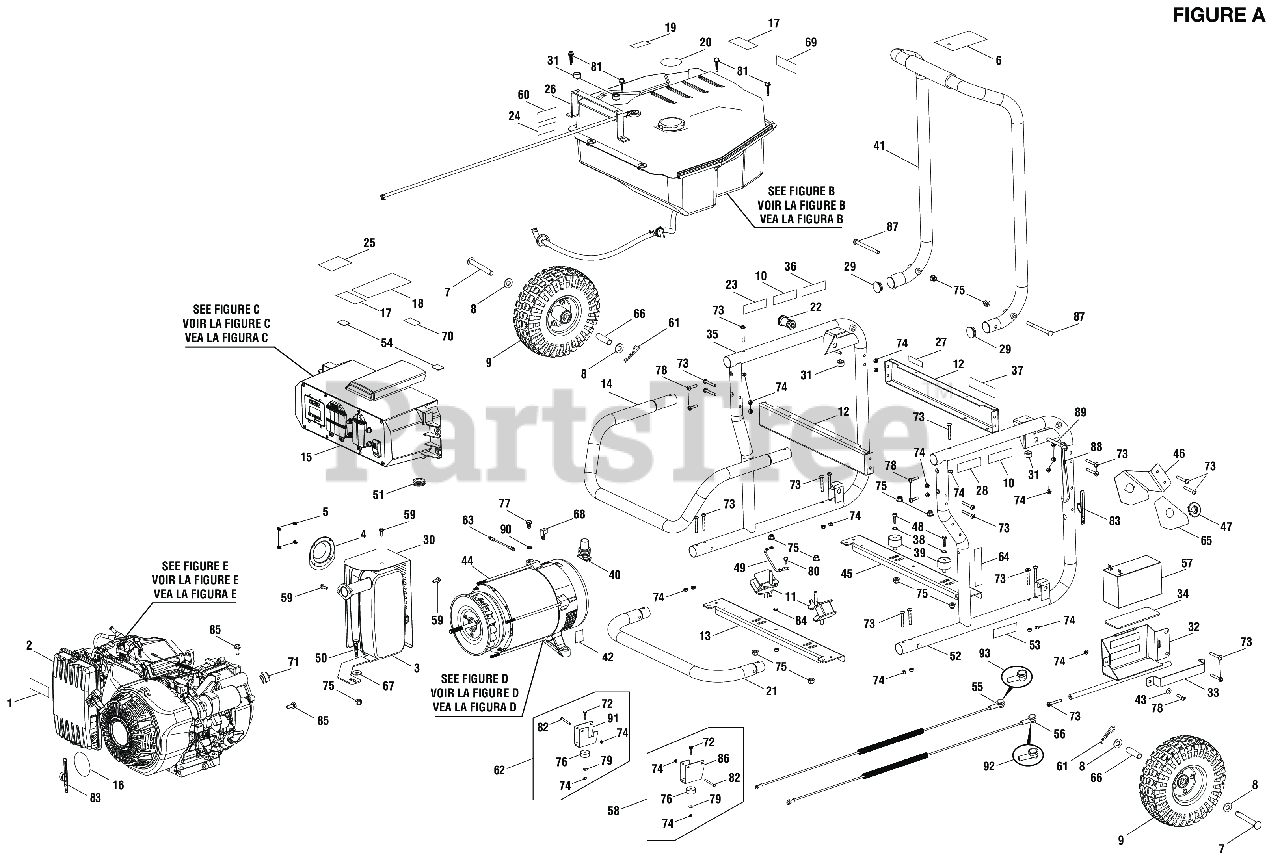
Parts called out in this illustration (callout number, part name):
1	Choke Label
2	Engine
3	Muffler w/Brackets
4	Spark Arrester Screen
5	Screw (8-32 x 3/8 in., Pan Hd.)
6	Warning Hangtag
8	Washer (1/2 in.)
9	Wheel (10 in. x 3 in.)
10	LABEL, ZERO GRAVITY
11	Vibration Isolator
12	CROSSMEMBER, FUEL TANK
13	CROSSMEMBER, ENGINE, RIDGID
14	FRONT TUBE, TOP RIDGID
15	ASSEMBLY, WIRED PANEL RD907500P
16	LABEL, RECOIL, RIGID 420CC OHV
17	LABEL, LOGO RIDGID
18	LABEL, PERFORMANCE RD907500P
19	No E85 Label
20	Fuel Stabilizer Label
21	FRONT TUBE, BOTTOM
22	RELEASE PIN CM80034
23	Fire Distance Label (Eng/Sp)
24	Hot Surface and Exhaust Label
25	CPSC Danger Label
26	BRACKET, WRAPPER BOX SUPPORT
27	LABEL, INQUIRES RIDGID GENERATORS
28	Risk of Fire Danger Label
29	End Cap (Handle)
30	Heat Shield
31	Rubber Bumper
32	BATTERY BOX ASSEMBLY, SMALL
33	BATTERY RETAINING BRACKET ASSEMBLY, GRAY
34	Gasket (Battery Hold Down Bracket)
35	RIGHT FRAME ASSEMBLY
36	Quick Release Pin Label
37	Ground Warning Label
38	Lock Washer (OD14.8 x ID8.5 x 1t)
39	Isolator Generation 7
40	Rubber Boot
41	HANDLE ASSY W/ CAPS
42	Ground Label Icon
43	Washer (1/4 in.)
44	GEN HEAD ASSEMBLY 7.5KW <6% THD SHENFA
45	CROSSMEMBER, GEN-HEAD, RIDGID
46	BRACKET, FUEL VALVE, RIDGID
47	Fuel Valve Bezel
48	Bolt (M8 x 1.25 in., Hex Hd.)
49	Ground Wire Assembly
50	Screw (M8 x 40 mm, Hex Hd.)
51	GROMMET 16mm ID
52	LEFT FRAME ASSEMBLY
53	Engine Lubricant Label
54	RUBBER ISOLATOR
55	BATTERY CABLE RED
56	Battery Cable (Black 390 mm)
57	Battery Bracket
58	LEFT FOOT ASSEMBLY, BLACK
59	Bolt (M6 x 9 mm, Hex Flange Hd.)
60	UL Fire Warning Label Spark Arrestor)
61	Hitch Pin (M3)
62	Superseded by 310739009
63	WIRE, BONDING 95MM 10AWG
64	LABEL, QUICK START JD 420CC E-START
65	LABEL, FUEL VALVE ON/OFF
66	Axle Spacer
67	Washer (ID9 x OD25.4 x 2t)
68	Ground Lug (1/4-20)
69	Warning Label
70	Electric Start Label
71	Plug (Generator Head)
72	Superseded by 660224019
73	Bolt (M6 x 42 mm, T30 Torx Hex Hd.)..
74	Lock Nut (M6 x 1 mm)
75	Flange Lock Nut (M8 x 1.25 mm)
76	Rubber Wear Pad
77	Bolt (M8 x 15 mm, Hex Hd.)
78	Bolt (M6 x 25 mm,T30 Torx Pan Hd.)
79	Washer (OD17 x ID6.4 x 1.6t)
80	Screw (M6 x 16 mm, Hex Hd.)
81	Screw (1/4-14 x 1.25 in., Hex Flange Hd.)
82	Bolt (M6 x 25 mm, Hex Hd.)
83	J-Clamp Flexible
84	Star Washer (M6)
85	Bolt (M8 x 20 mm, Hex Hd.)
86	FOOT, LEFT
87	Handle Pivot Bolt (M8 x 98 mm, Flat Hd.)
88	BUNGE CORD RETAINER
89	Release Pin (5/16 x 2 in.)
90	Star Washer (M8)
91	FOOT, RIGHT
92	Rubber Battery Cable Boot (Black)
93	Rubber Battery Cable Boot (Red)
